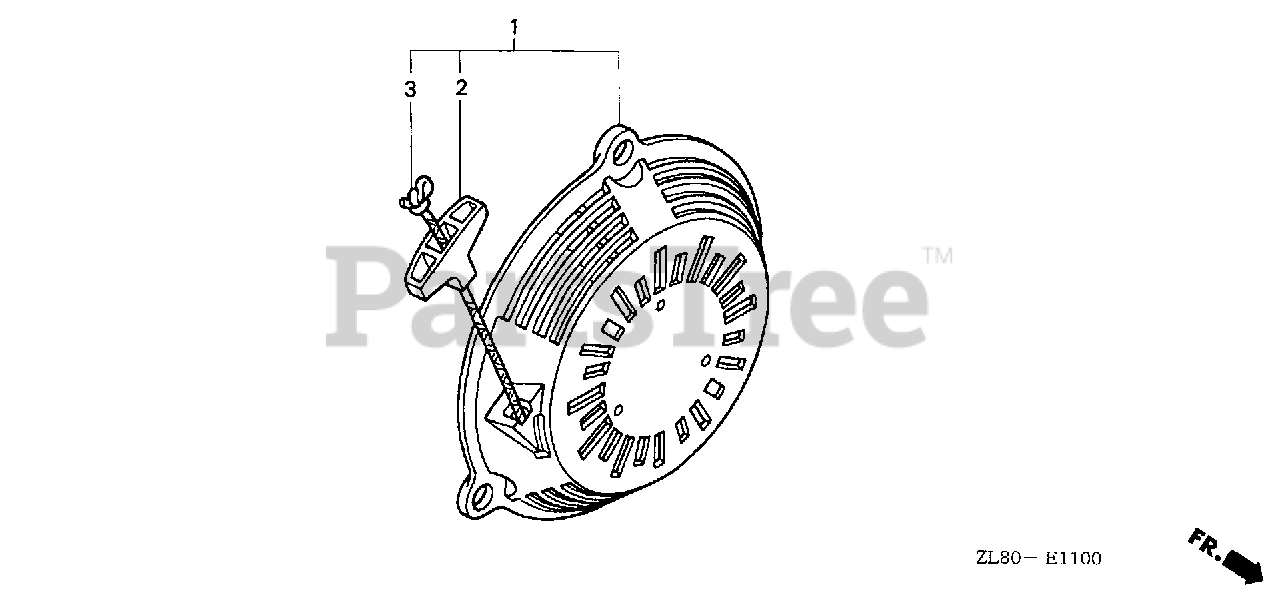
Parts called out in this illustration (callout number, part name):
1	STARTER ASSY., RECOIL *NH1* (BLACK)
2	GRIP, STARTER
3	ROPE, RECOIL STARTER
